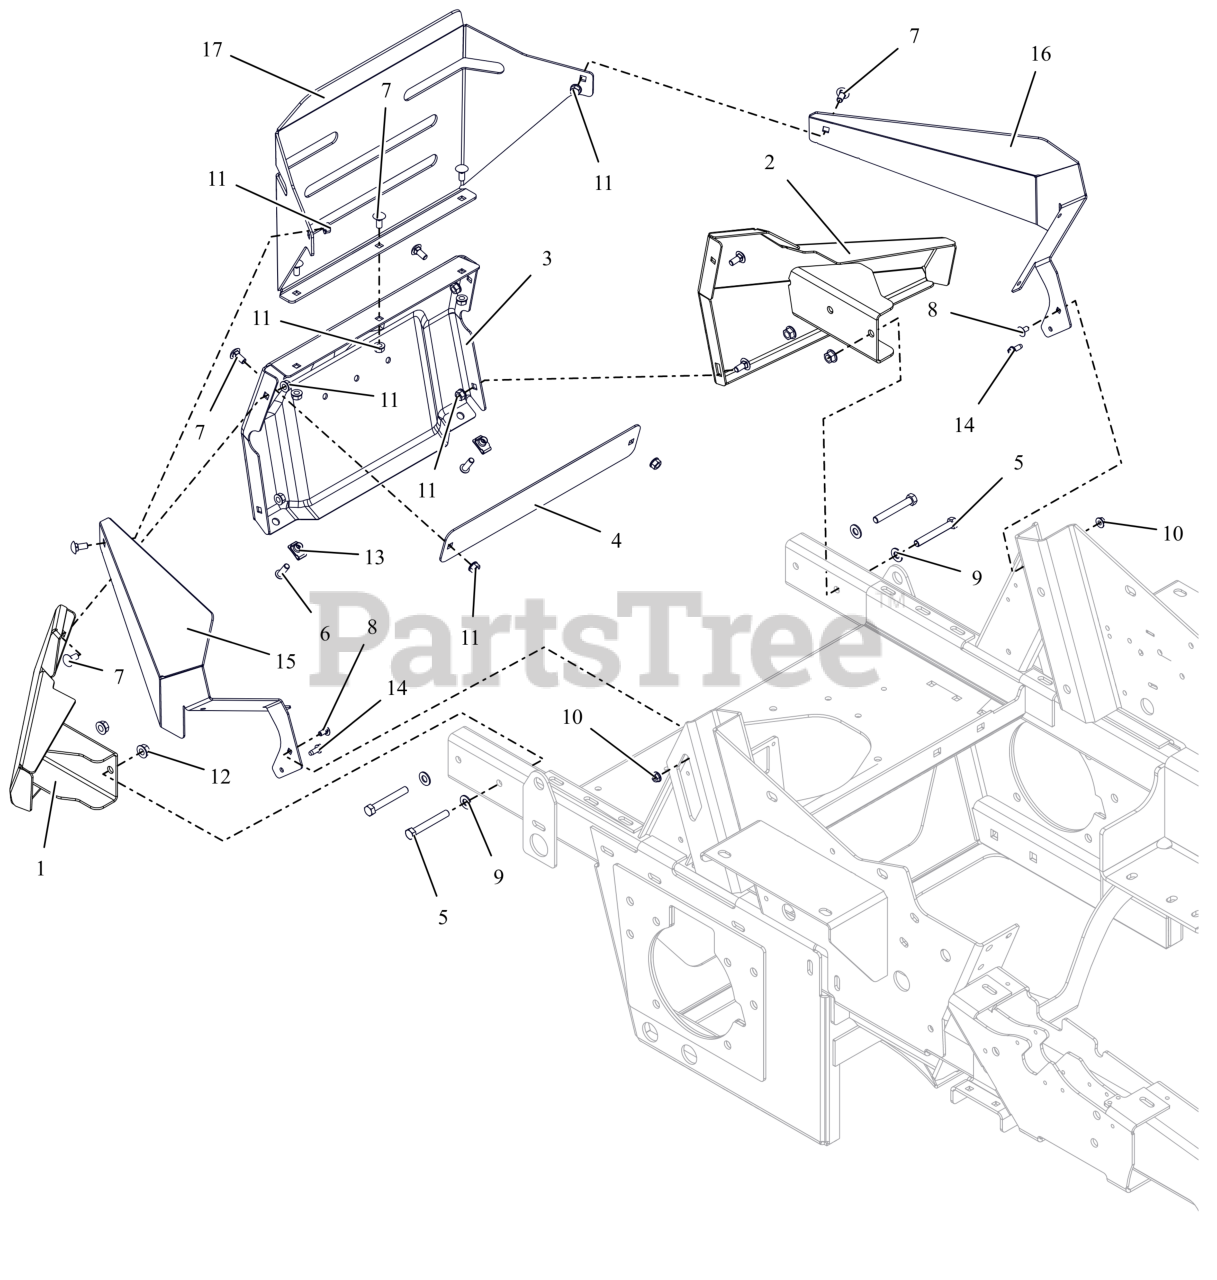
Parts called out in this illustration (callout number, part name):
1	WLDMT, RIGHT REAR BUMPER WING (RED) W/ SAFETY DECALS
2	WLDMT, LEFT REAR BUMPER WING (RED) W/ SAFETY DECALS
3	BUMPER, COMMERCIAL REAR
4	PLATE, BACKER (BLACK)
5	BLT, HEX .38-16X2.75 G5 ZCC
6	BLT,SHCS-BTN .31-18X1.00 ZCC
7	BLT,RHSN .31-18X.75 G5 ZCC
8	BLT, RHSSN.25-20X.500 G5 ZCC
9	WSHR,FLT .406X.812X.065 ZCC
10	NUT-LK-CTR-FLG .25-20 ZC120
11	NUT,LK-CTR-FLG .31-18 GF ZCC
12	NUT-LK-CTR-FLG .375-16 GF ZCC
13	NUT-CLIP RETAINER 5/16-18X.56
14	SCR,TAP .25-20X.625 HWH ZCC
15	BRKT- RH SIDE WRAP MTG
16	BRKT- LH SIDE WRAP MTG
17	WRAP, PT500 REAR CENTER (BLACK)
